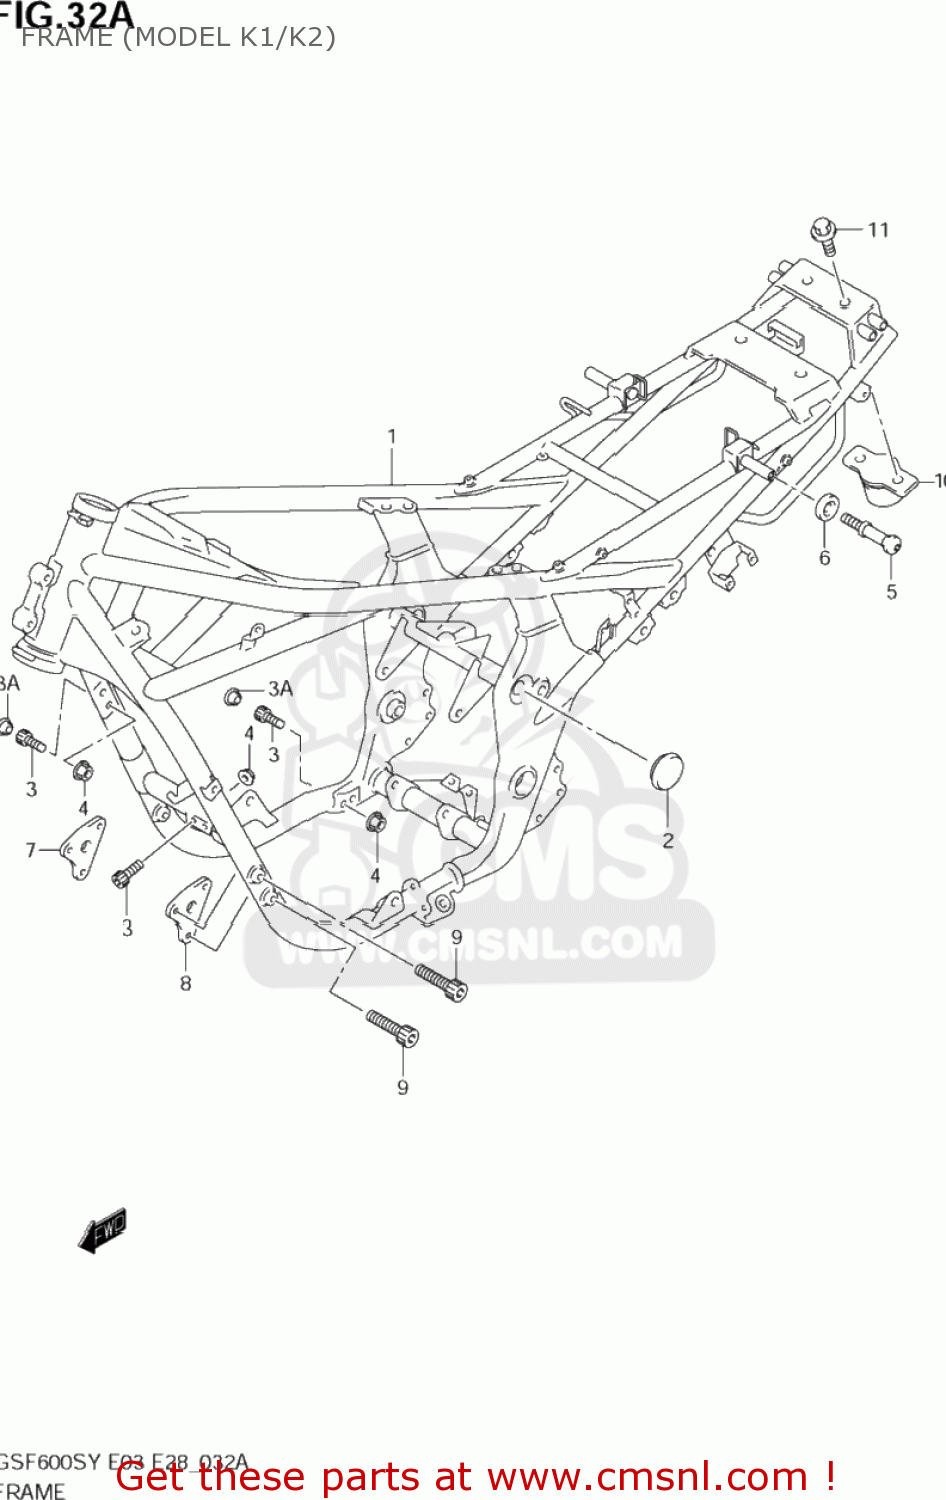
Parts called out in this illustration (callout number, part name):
1	FRAME COMP
2	CAP,FRAME BODY
3	BOLT(10X37)
3A	CAP(OD:12)
4	NUT
5	HOOK,SEAT RAIL
6	WASHER,HOOK
7	PLATE,ENG MTG,R
8	PLATE,ENG MTG,L
9	BOLT
10	DAMPER,FRAME RR
11	BOLT
